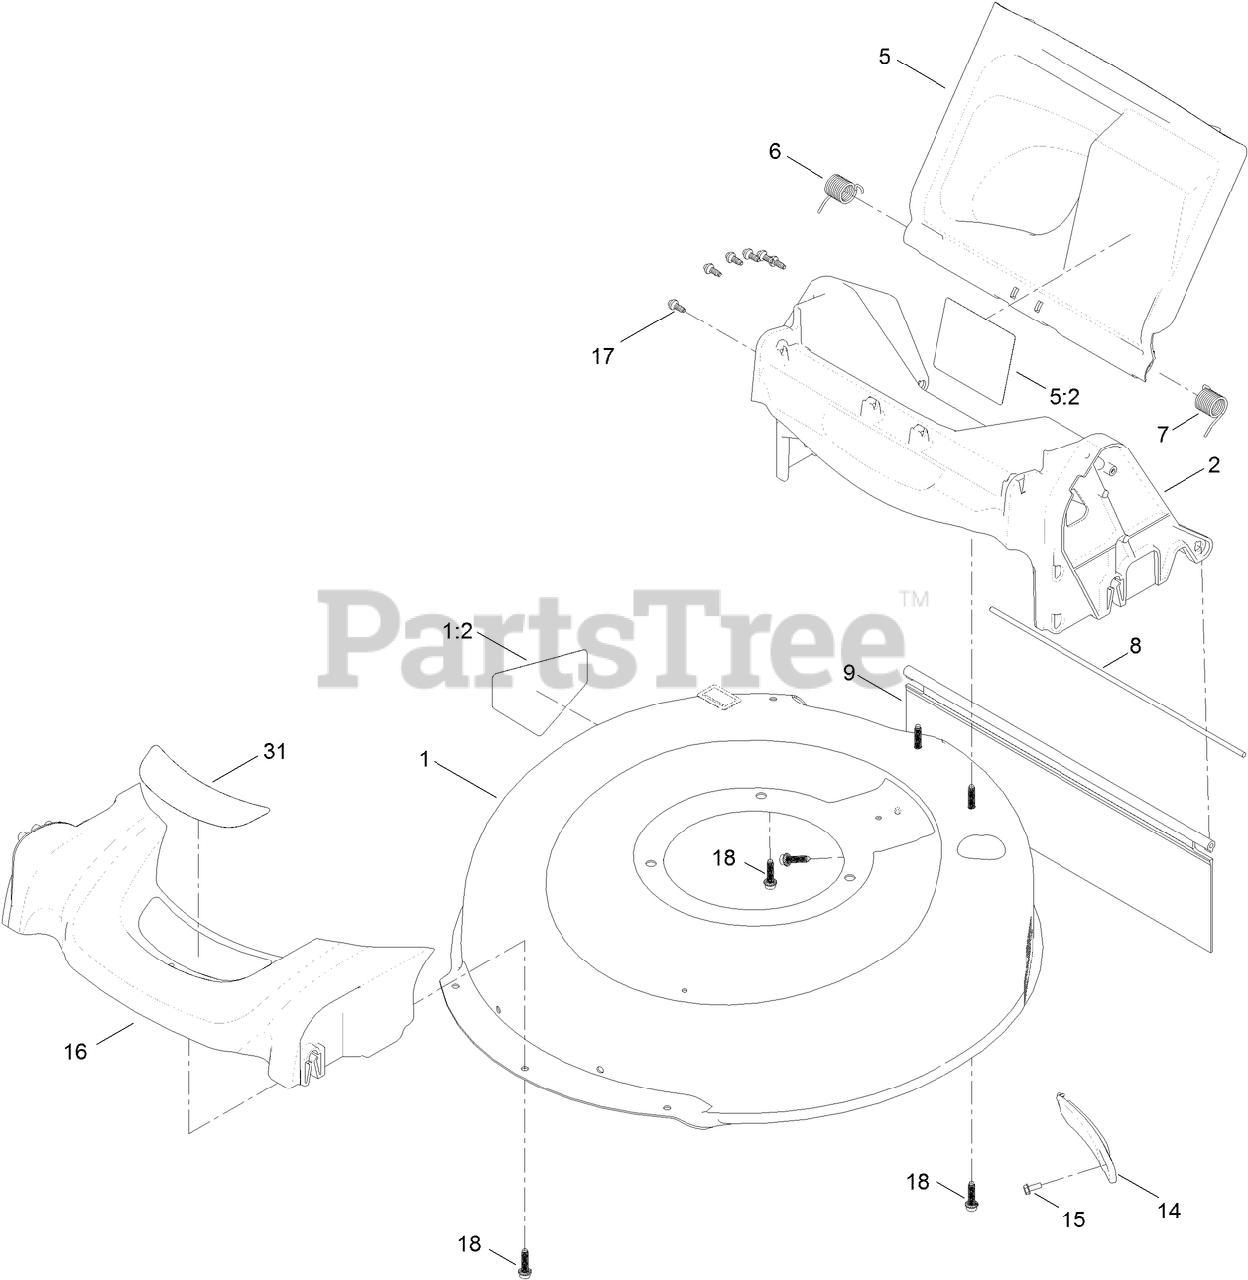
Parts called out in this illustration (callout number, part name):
1:2	DECAL-DANGER
2	CHUTE ASM
5	REAR DEFLECTOR ASM
5:2	DECAL-WARNING
6	SPRING-TORSION
7	SPRING-TORSION
9	SHIELD-TRAILING
14	COVER-BELT
15	SCREW-TAPTITE
18	SCREW-FLANGE, PLASTIC
31	DECAL-DECK
